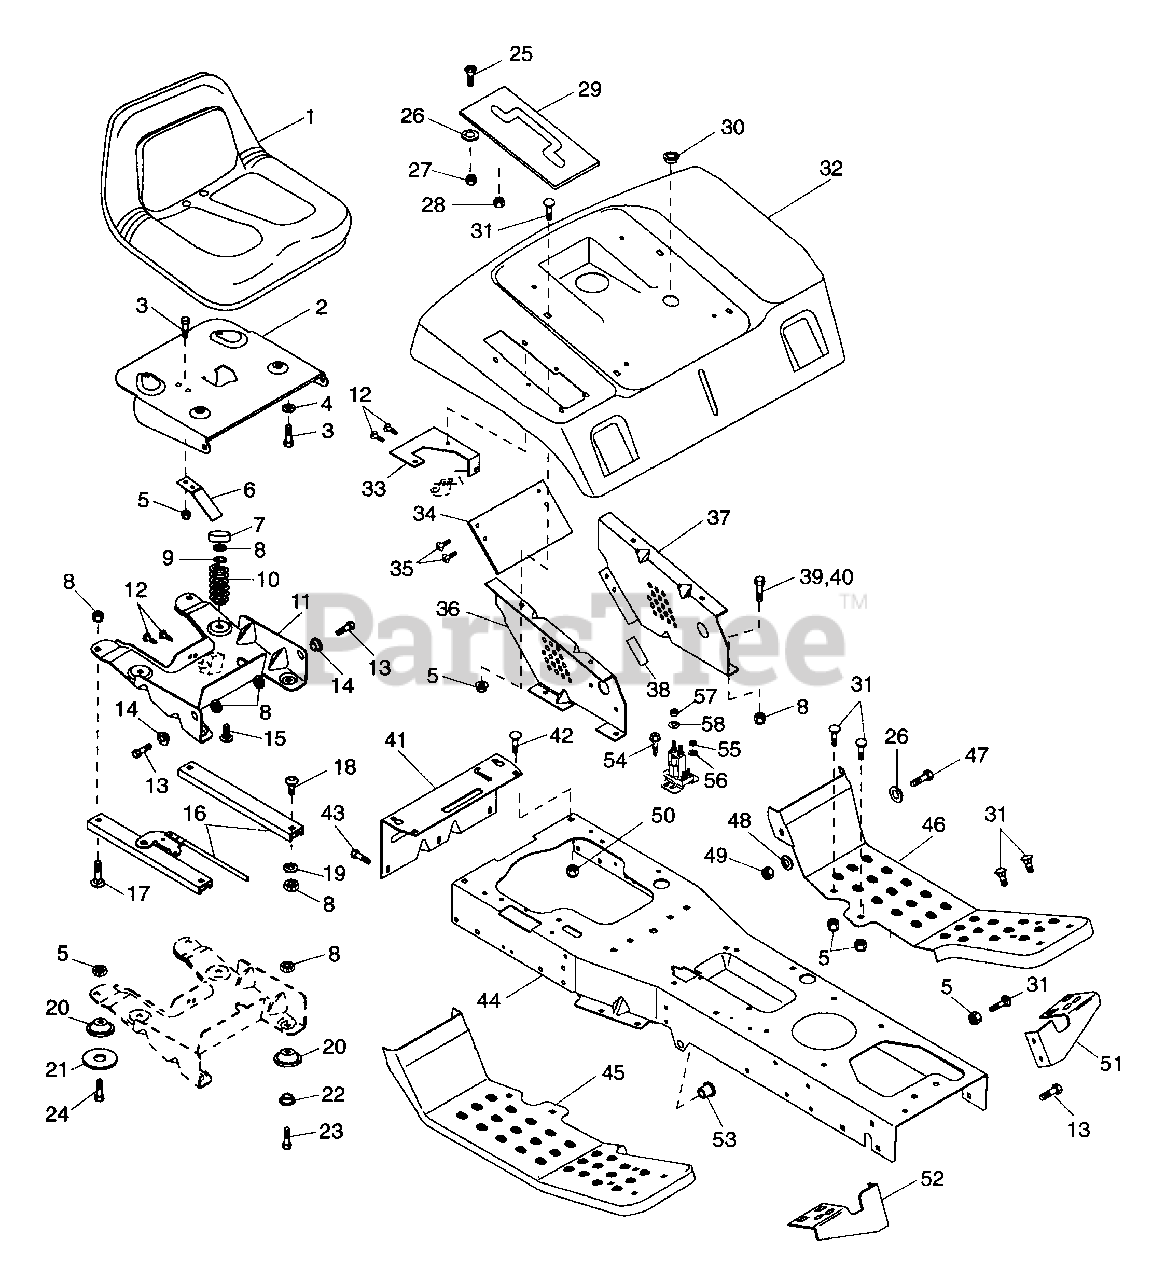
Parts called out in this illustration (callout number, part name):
1	SEAT- V-560
2	SEAT PIVOT PLATE
3	BLT-HEX .31-18X.75 PL GR2
4	WSHR-LK .312X.097 PL HVY
5	NUT-FLG. .312-18 PL
6	SPRING PLATE
7	TUBE CAP
8	NUT-LK .312-18 GR A PL
9	WSHR-FL-STL.344X.688X.065PL
10	SG-COMP .148X1.23X2.41 WLD87
11	BOX, SEAT
12	SCR-TAP 12-24X.50 HWH PL TR
13	BLT-HEX .31-18X.75 PL GR5
14	BSHG-FLG .325X.465X.333X.685
15	BLT-RDHDSQNK.31-18X.75GR5SHTPL
16	SEAT SLIDES -(RAME TAK-3010-4)
17	BLT-RDHDSQNK .312-18X.62SHTPL
18	SCR-CAP BTHD.31-18X.50 GR5 YZ
19	WSHR-FL-STL .328X.875X.062 PL
20	SEAT SPACER
21	WSHR-FL-STL .508X1.62X.105 PL
22	BSHG-FLG .325X.500X.500X1.250
23	BLT-HEX .31-18X1.25 PL GR2
24	BLT-RDHDSQNK .31-18X1.00 PL
25	SCR-MCH .25-20X .75 CRFL PL
26	WSHR-FL-STL.281X.62X.065 PL
27	NUT-LK-NYL .250-20 PL
28	NUT-SELF-THRDNG FITS.25 STUDPL
29	INSERT- 5 SPEED PLASTIC
30	SNAP BUSHING
31	BLT-RDHDSQNK .312-18X.62SHTPL
32	REAR DECK- YT
33	SWITCH MOUNT
34	BACK PLATE
35	SCR-TAP 10-24X.375 CRPH 1A
36	RIGHT DECK SUPPORT
37	LEFT DECK SUPPORT
38	PAD, FOAM
39	BLT-HEX .31-18X.63 PL GR 2
40	BLT-HEX .31-18X1.00 PL GR 2
41	DRAW BAR
42	BLT-RDHDSQNK .375-16X.75 GR5PL
43	SCR-TAP .312-18X.75 HWH PL TR
45	RIGHT FOOT REST
46	LEFT FOOT REST
47	BLT-HEX .25-20X.63 PL GR2
48	WSHR-LK .250X.077 HVY PL
49	NUT-HEX .250-20 PL
50	NUT-LK-CTR .375-16 GR A PL
51	LH FOOT REST BRACE
52	RH FOOT REST BRACE
53	BSHG-FLG .515X.750X.745X1.00NY
54	SCR-TAP .250-20X.37 HWH PL TR
55	BSHG-FLG .625X.750X.500X.875BR
56	WSHR-LK-EXT #10 ID X .022
57	NUT-JAM .312-24 PL
58	WSHR-LK-INT .313X.030 PL
